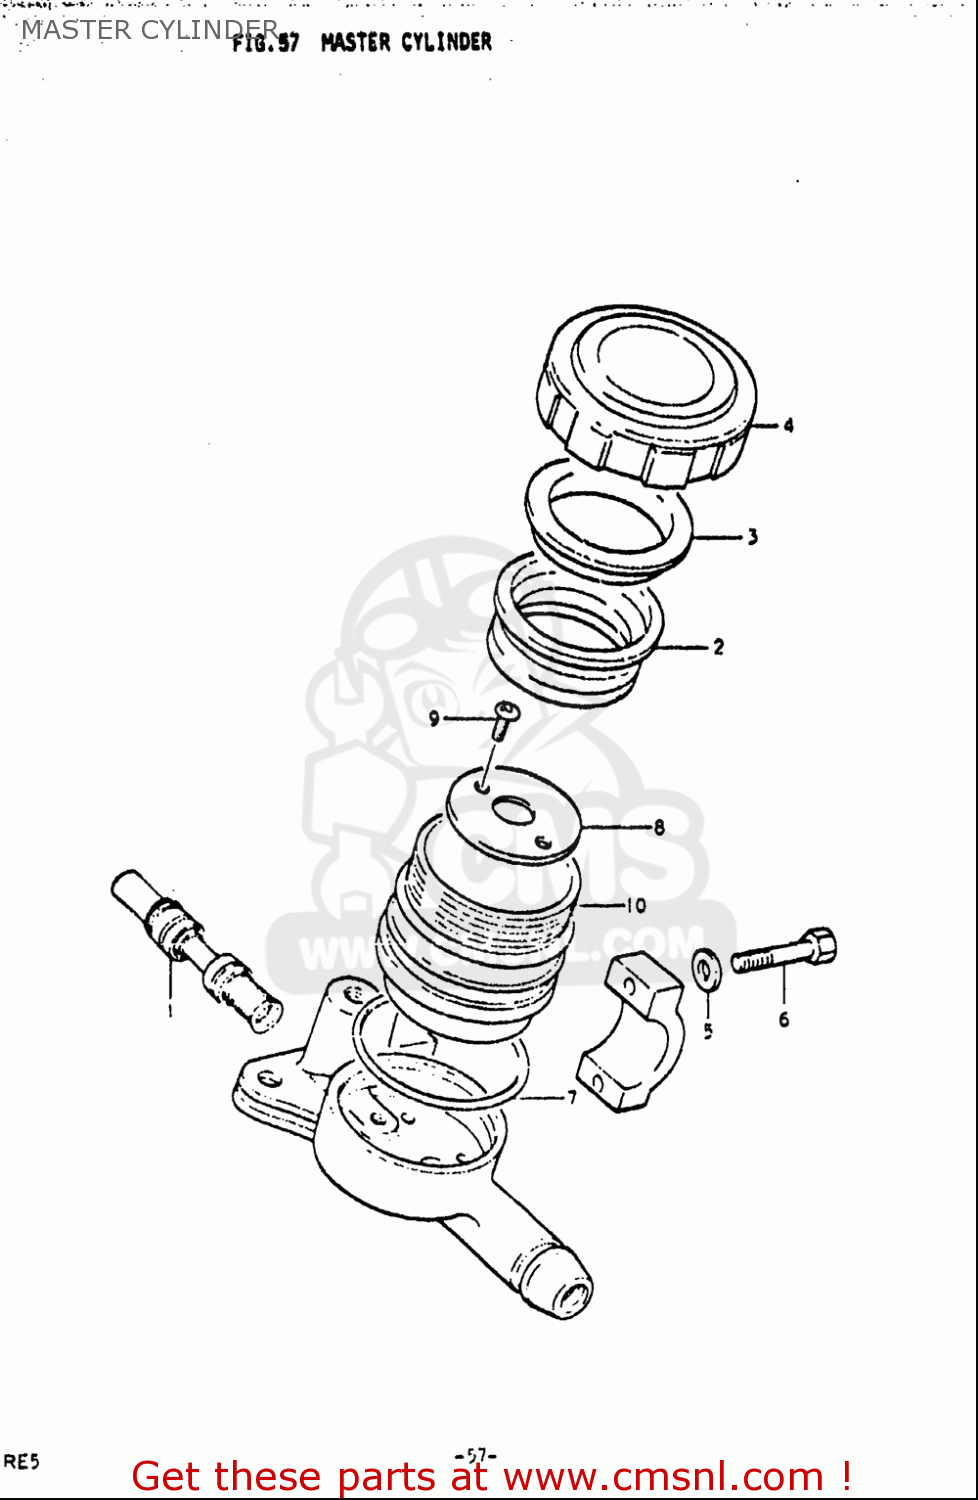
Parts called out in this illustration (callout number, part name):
1	PISTON & CUP SET
2	DIAPHRAGM
3	PLATE,DIAPHRAGM
4	CAP
5	WASHER
6	BOLT
7	O RING
9	SCREW
10	RESERVOIR
